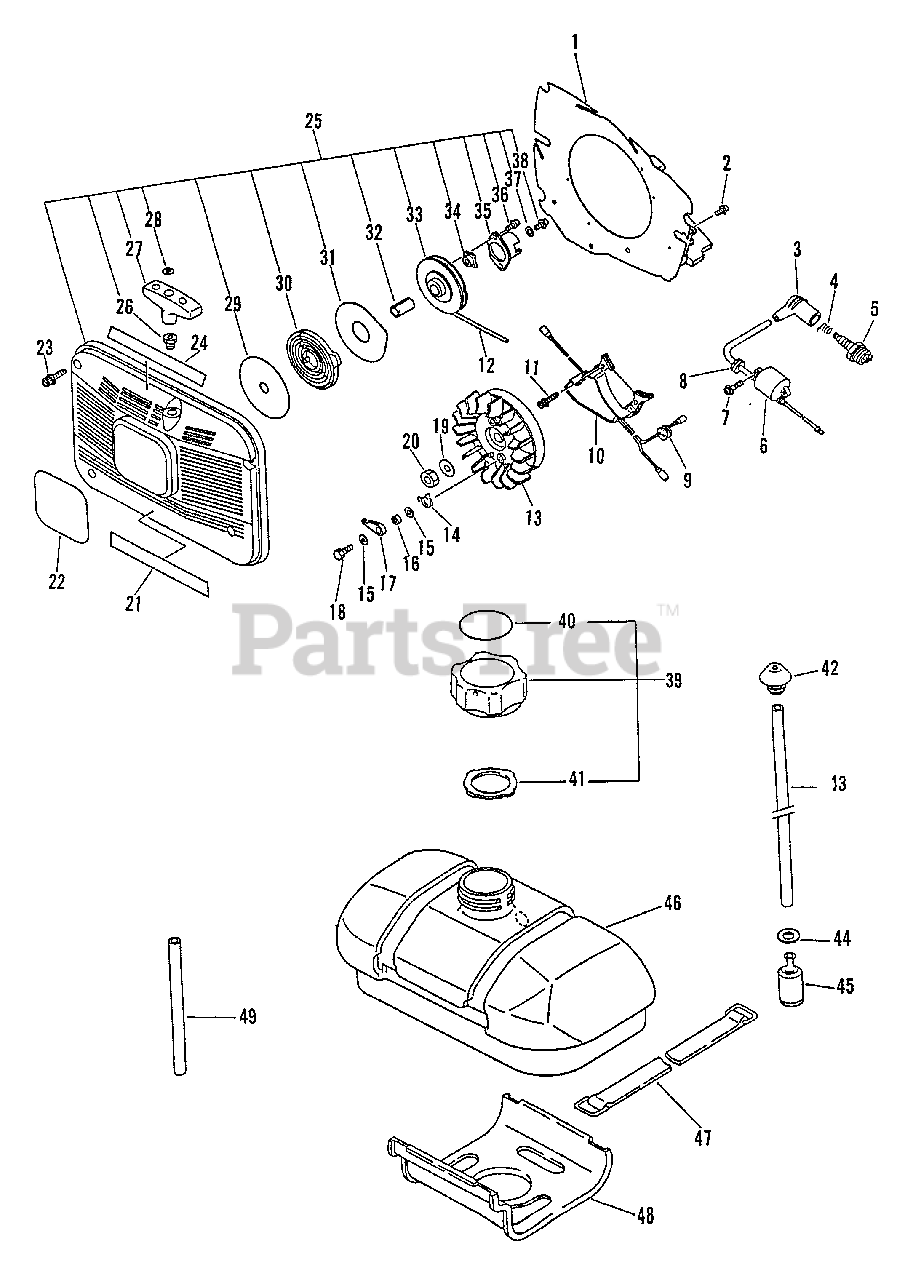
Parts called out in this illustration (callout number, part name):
1	PLATE
2	SCREW - 4X12
3	CAP, SPARK PLUG
4	TERMINAL, SPARK PLUG CAP
5	SPARK PLUG -- BPM-7A
6	COIL, IGNITION
7	SCREW - 4X14
10	COIL, IGNITION
11	SCREW - 4X18
12	ROPE, STARTER - 4X950
13	FLYWHEEL
14	SPRING, RETURN
15	WASHER - 5
17	PAWL, STARTER
18	BOLT - 5X16
19	WASHER - 10
20	NUT - 10
21	LABEL - CAUTION
22	LABEL - MODEL REC-600
23	SCREW - 5X20
24	LABEL - CAUTION
25	STARTER ASSY
26	GUIDE, ROPE
27	GRIP, STARTER
28	RING, RETAINING
29	PLATE, STARTER
30	SPRING, REWIND
31	PLATE, STARTER
33	REEL, ROPE
34	RETAINER, ROPE
35	CATCHER, PAWL
36	SCREW - 4X10
37	WASHER - 5
38	SCREW - 5X10
39	CAP ASSY
40	LABEL - FUEL MIX
41	GASKET, CAP
43	PIPE - 3X6X220 -- BLACK
44	WASHER - 5
45	FILTER, FUEL
46	TANK, FUEL
47	STRAP
48	CUSHION, FUEL TANK
49	PIPE - 3X6X150 -- BLACK
